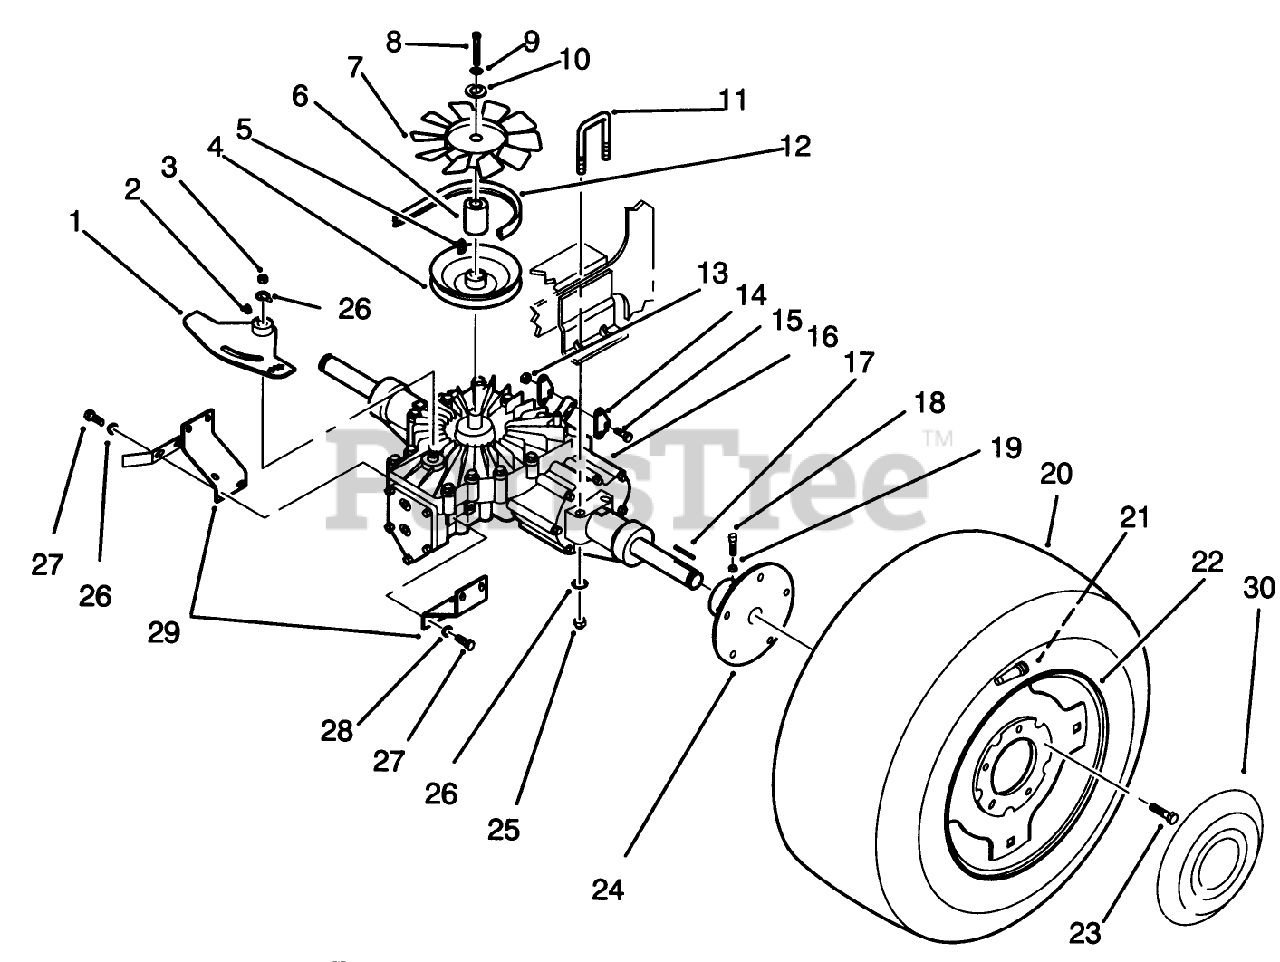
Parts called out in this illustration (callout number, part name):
1	WLDMT-CONTROL ARM
2	KEY WOODR 1/8X1/2 DI
3	PINION SHAFT
5	HARD HI PRO KEY
6	SPACER
7	FAN-7"
9	WASHER-LOCK
10	WASHER
11	U-BOLT
12	BELT-V
13	NUT-LOCK, NI
15	SCREW-HH
16	751-TRANSAXLE
17	KEY-SQUARE
18	Screw-Set
19	NUT-JAM
21	VALVE
22	WHEEL
23	BOLT-LUG
25	NUT-LOCK, NI
26	WASHER-FLAT
27	SCREW-HH
28	WASHER-FLAT
